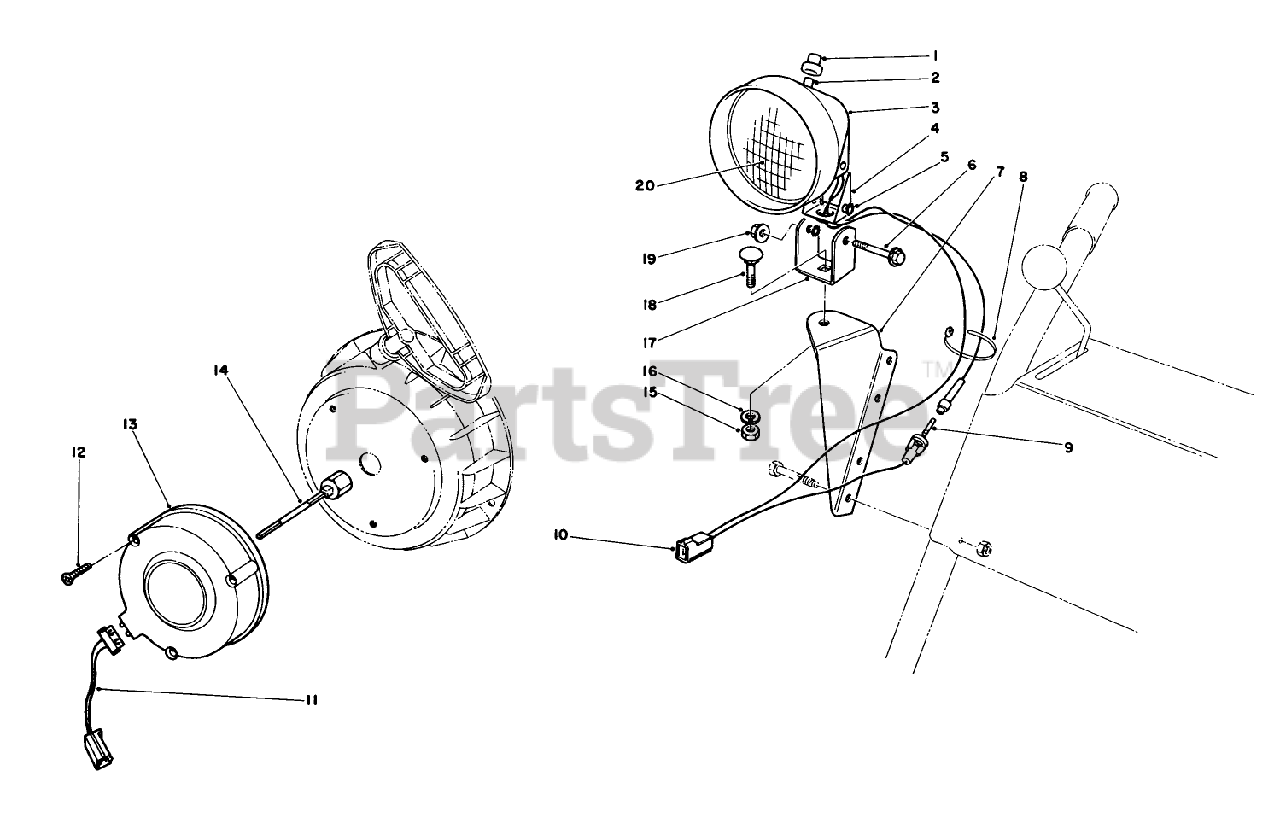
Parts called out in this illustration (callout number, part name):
1	BOOT-SWITCH
5	WASHER-LOCK
6	SCREW-HH
7	MOUNT-LAMP
8	TIE-CABLE
9	Fuse-7 1/2 Amp
10	WIRE ASM
13	TECUMSEH 1A183-69
15	NUT-HEX
16	WASHER-LOCK
18	BOLT-CARR
19	NUT-HF
